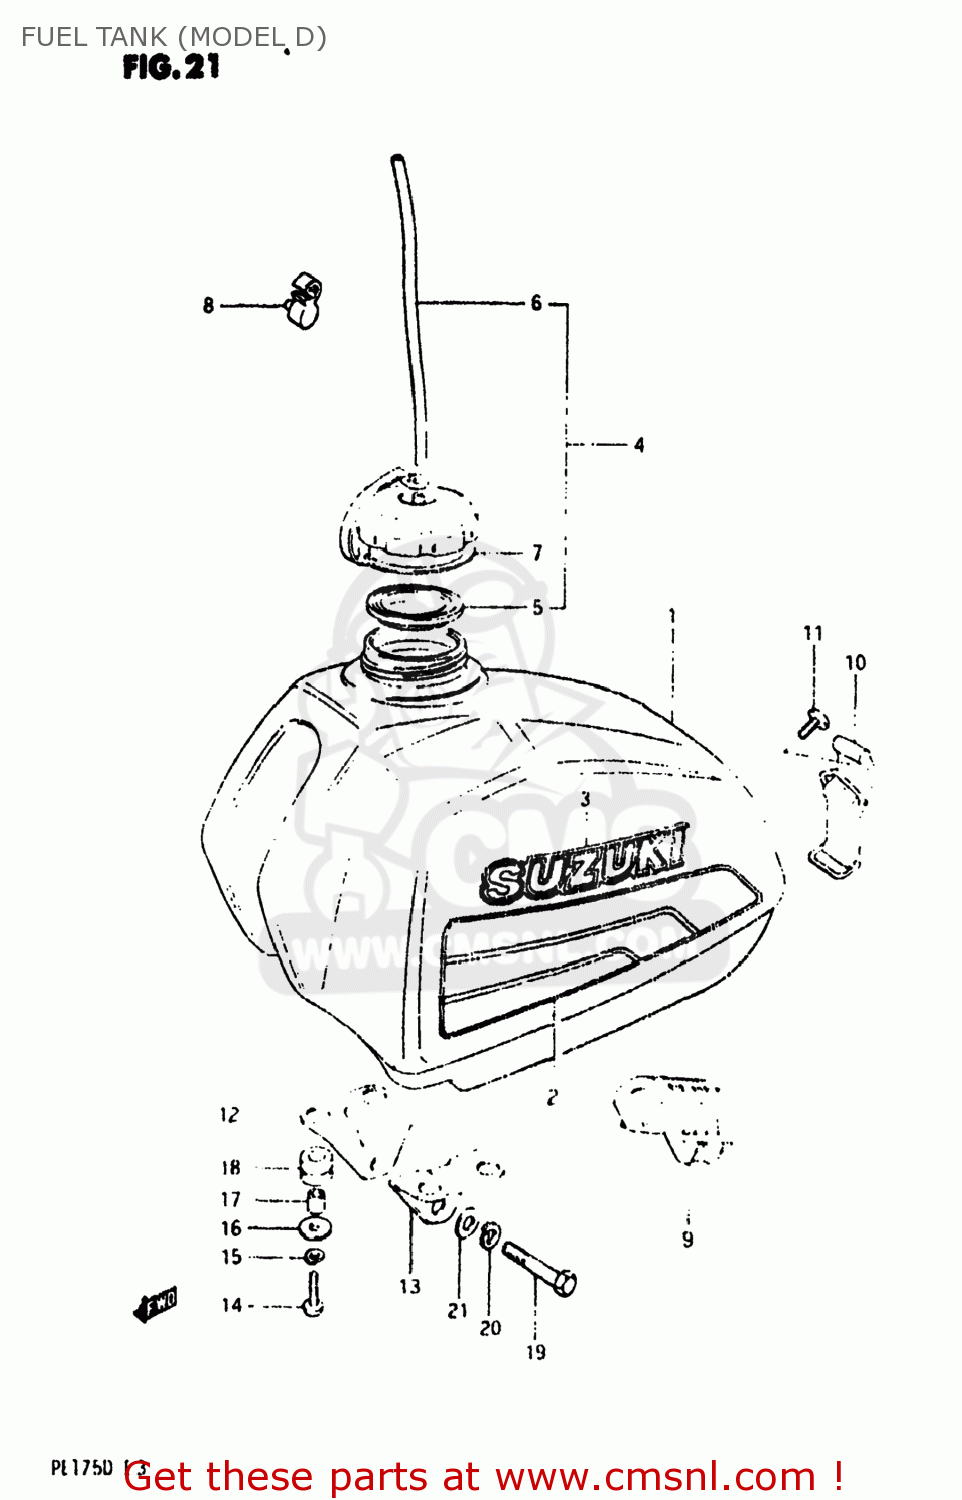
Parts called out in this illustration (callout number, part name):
1	TANK ASSEMBLY,FUEL
2	TAPE SET,FUEL TANK
3	EMBLEM
4	CAP,FUEL TANK
5	GASKET,FUEL TANK CAP (NAS)
6	HOSE
7	BAND,FUEL TANK CAP
8	CLAMP,BREATHER HOSE
9	CUSHION,FUEL TANK
10	BAND,FUEL TANK,REAR
11	SCREW(6X18)
12	BRACKET,FUEL TANK,LOWER
13	BRACKET,FUEL TANK
14	SCREW
15	LOCK WASHER
16	WASHER (6.5X24X1.6)
17	SPACER(6.8X12X11)
18	CUSHION
19	HEXAGON BOLT 8X80
20	LOCK WASHER
21	WASHER
